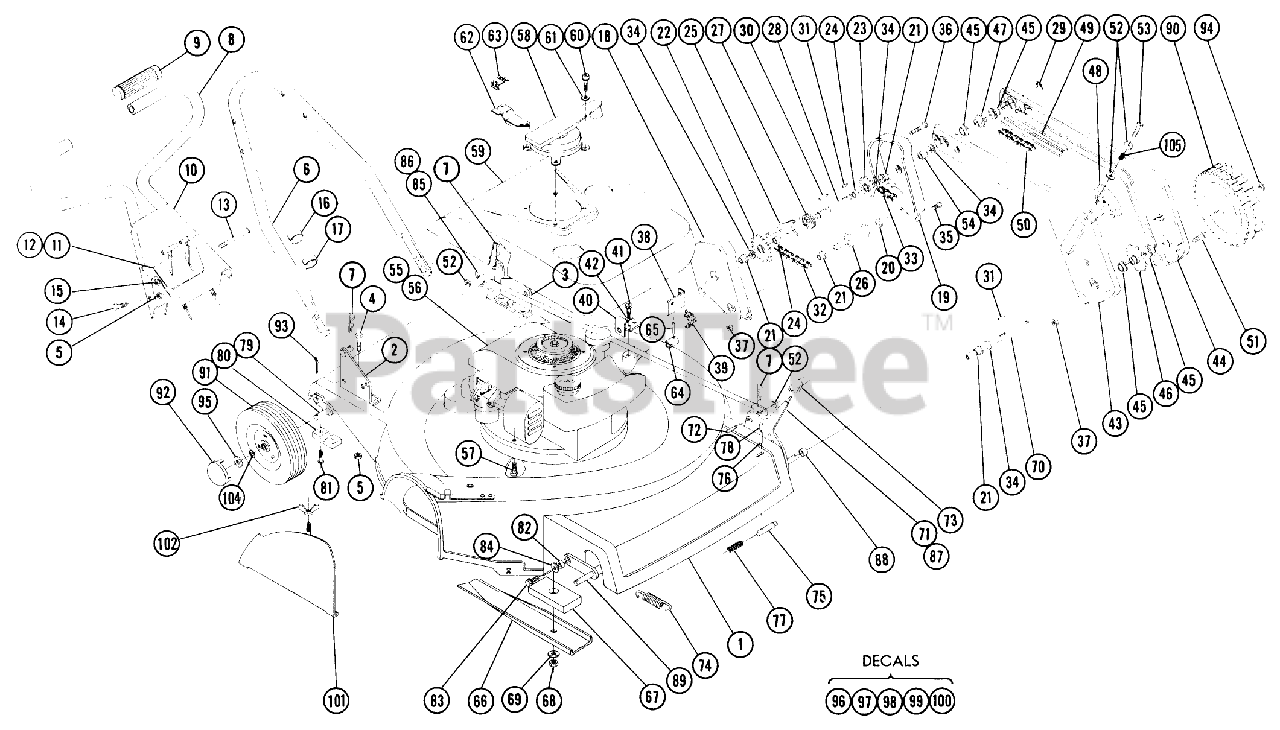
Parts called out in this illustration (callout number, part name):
1	Ass-y. Deck
2	Ass-y. Bracket-Handle R.H.
3	Ass-y. Bracket-Handle L.H.
4	Bolt 5/16-18 x
5	Nut-Nylok
6	Ass-y Handle-Lower
7	Hairpin
8	Handle-Upper
9	Grip-Handle
10	Plate-Control MT-G
11	Control Throttle
12	Control-Throttle Clutch
13	Screw-Fil. Hd. 1/4-20 x 3 1/4
14	Bolt-Hex. 5/16-18 x 1
15	Nut 1/4-20 Keps
16	Clip-Double
17	Clip-Single
20	BUSHING
21	BRONZE BUSHING
22	Ass-y. Sprocket Hub
23	Ass-y. Sprocket Hub
24	Bearing
26	Ass-y. Input Shaft Sprocket
27	Collar-Shift
28	Shaft-Output
30	HI PRO KEY
31	WOODRUFF KEY
32	Chain-Roller
33	Chain-Roller
34	Washer-Thrust
35	Bolt #10-32
36	Bolt #10-32 x 234 Round Head
37	HEX NUT 10-32 E.S. + + USE 3296-21 + +
38	Bracket-Shift Control
39	Clip-Tinnerman
40	Bracket-Trans. Support
41	Screw 1/4-20 x 5/8 S.T.
45	BUSHING
48	Guide-Upper
51	Screw-Machine #10-32 x 1 1/4
52	Washer
53	Nut Hex #10-32 Elastic Stop
55	87SIM-5637/38 WARDS
56	Ass-y. Engine
57	Bolt-Flg. 5/16-18 x 1
58	Ass-y. Starter-Impulse
59	Shroud
60	Screw L.W. Ass-y. 1/4-28 x 5/8 Fil. Hd.
61	Washer
62	Bracket-Starter Release
63	Clip-Tinnerman
64	Coupling
67	Drive Blade
69	Washer, 5/8
71	Ass-y. Lever-Height Adj.
72	Screw
75	HOSE BARB,1/4 NPT X 3/8
76	Roll Pin 1/8 x 1 1/8
78	Cap
79	Ass-y Axle-Rear
80	Cap-Rear Axle Support
81	Screw Hex 1/4-20 x 7/8 Self Tap
83	Screw L.W. Ass-y. 5/16-18 x 1 Hex S.T.
84	Washer 5/16 US
85	Rod-Wheel Adj. Link
86	Rod-Wheel Adj. Link
87	Ass-y. Lever-Height Adj. Front
89	Axle
92	Cap-Hub
93	Hairpin
94	Washer
95	Washer
96	4XC6485 GIS ROTARY
97	Decal-Height Indicator
99	Decal-Caution
100	Decal-Chain Adjustment
101	Ass-y Leaf Mulcher
102	Nut-Wing 1/4-20
104	Washer
